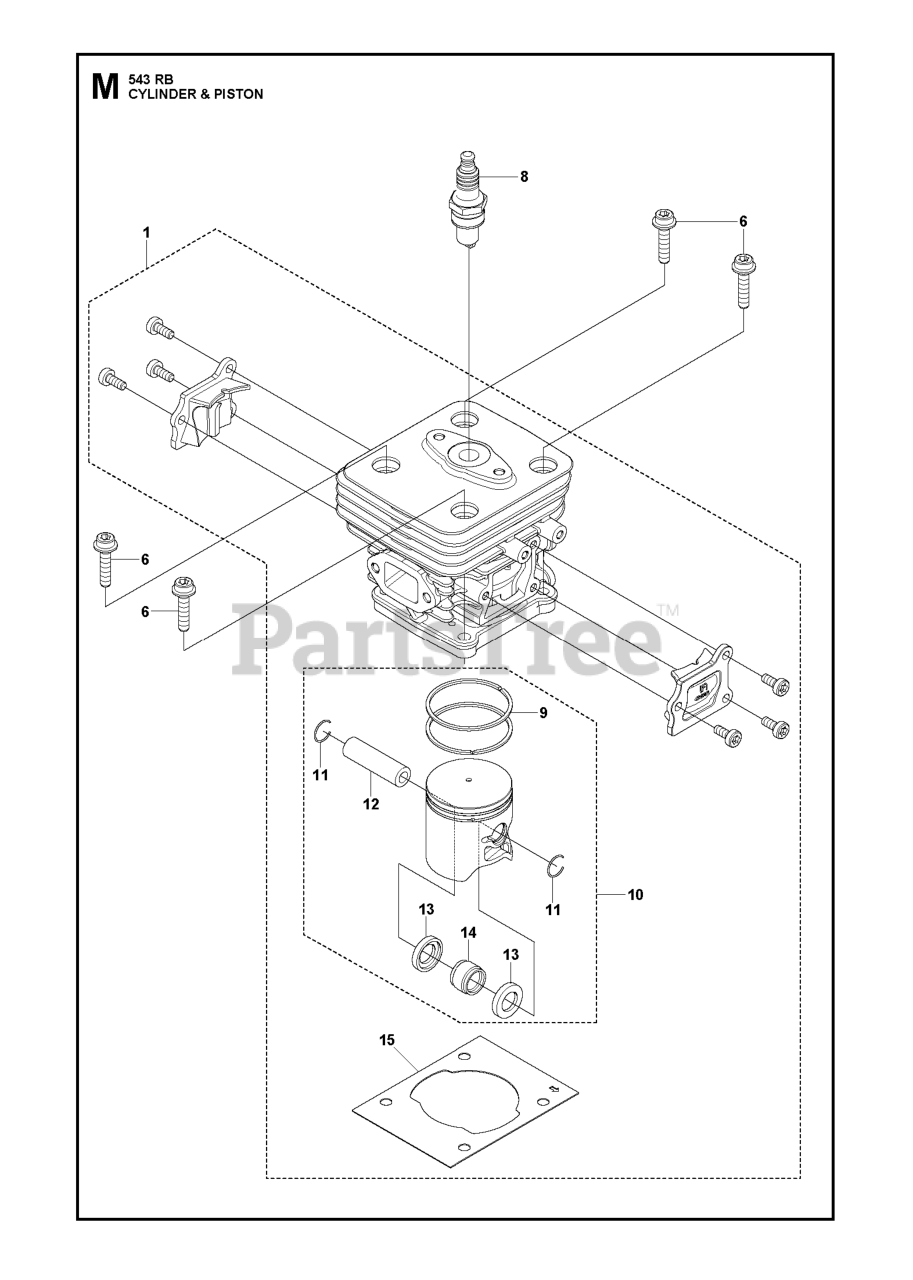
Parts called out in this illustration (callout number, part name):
8	SPARK PLUG CMR7H-10
9	RING PISTON
10	Service Kit
14	ROLLER BEARING
